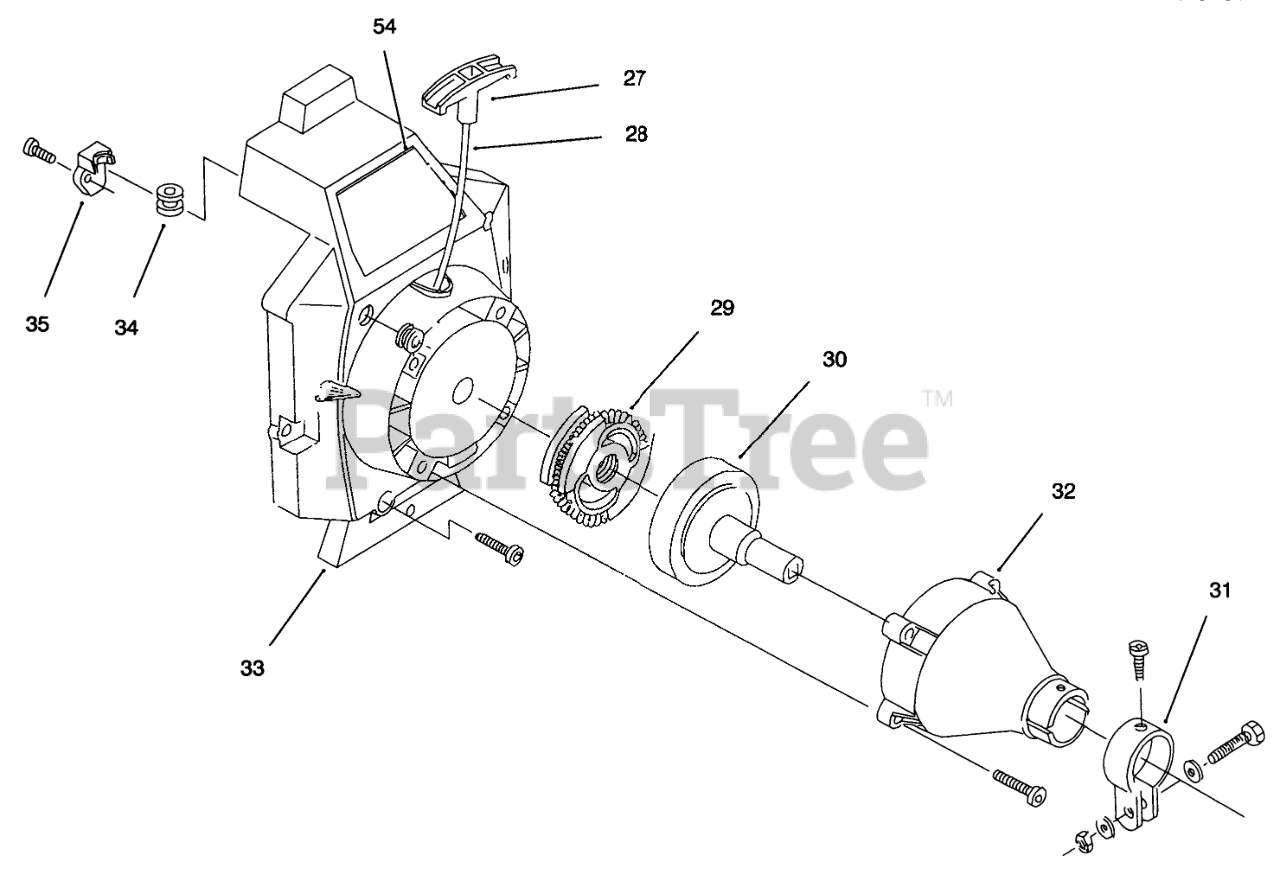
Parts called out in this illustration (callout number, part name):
27	Handle-Pull
29	Clutch Rotor Asm.
30	CLUTCH DRUM ASM
31	CLAMP ASM - UPPER
32	CLUTCH HSG ASM
33	STARTER HSG ASM
34	ROPE GUIDE
35	PULLEY RETAINER ASM
54	DECAL - TORO
